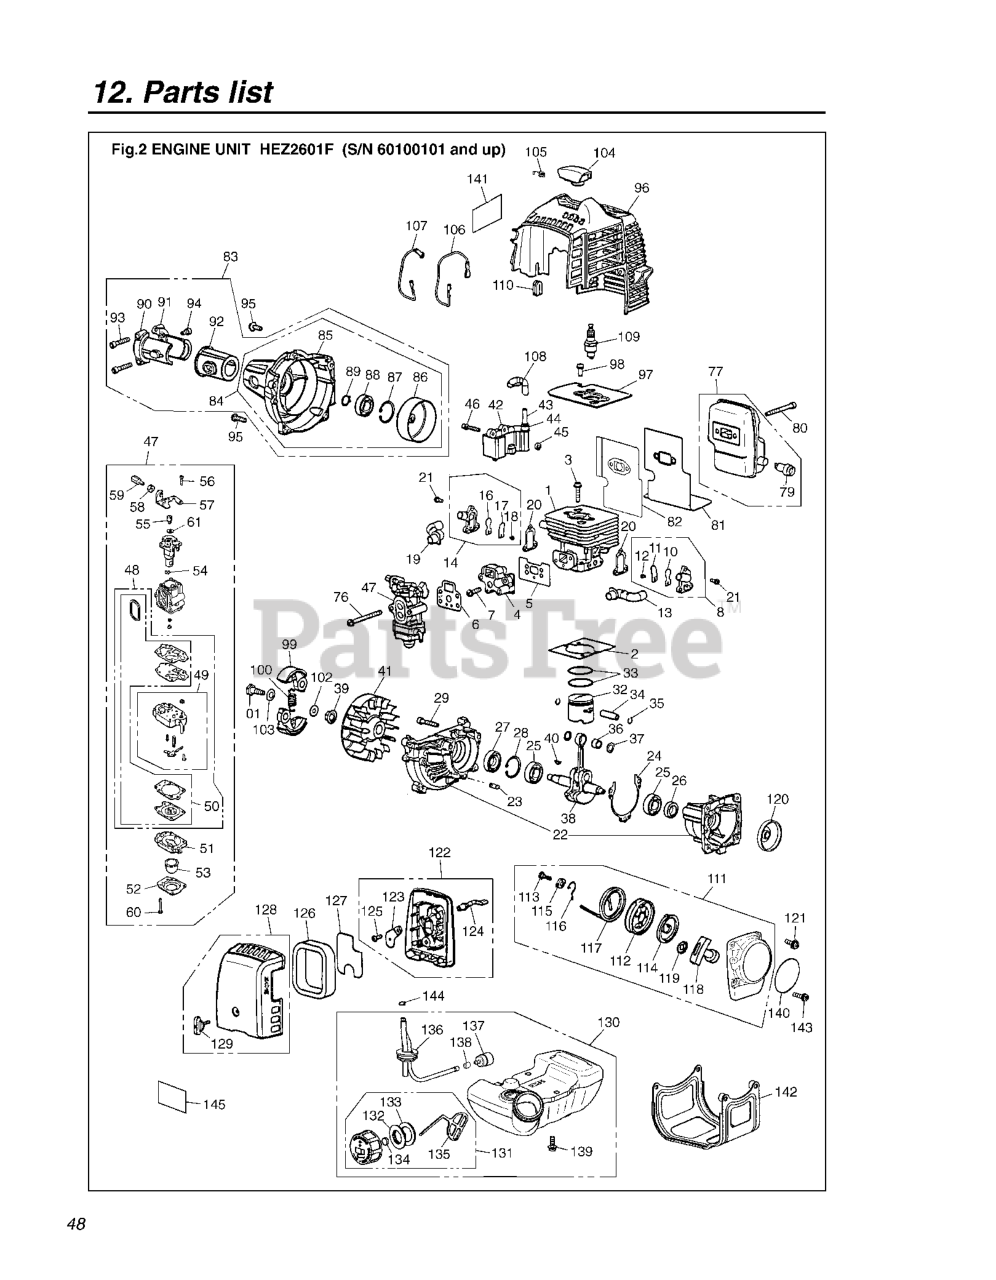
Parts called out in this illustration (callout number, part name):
1	CYLINDER
2	GASKET, BASE
3	BOLT
4	INSULATOR
5	GASKET.INSU
8	REEDVALVE (S) ASSY
10	REEDVALVE
13	PIPE AIR (S)
14	REEDVALVE (F) ASSY
16	REEDVALVE
19	PIPE AIR (F)
20	GASKET, VALVE
21	BOLT
22	CRANKCASE-C
23	PIN
24	GASKET.CASE
27	SEAL
34	PIN***
38	CRANKSHAFT COMP(RPLS481042000)
39	NUT
40	KEY
44	CAP
45	SPACER
47	CARBURETOR
48	REBUILD KIT
49	CARBURETOR BODY
50	GASKET KIT
52	1OVER
54	RING
55	SWIVEL
56	SCREW
57	BRACKET
58	NUT
59	ADJUSTER
61	WASHER
77	MUFFLER-A***
79	ARRESTER
82	PLATE, MUFFLER
83	HOUSING ASSY
84	COVER-C
85	COVER.FAN
88	BEARING
90	BRACKET(A)-24
91	BRACKET(B)-24
94	BOLT M5X14
96	COVER, ENGINE
104	CAP
107	CORD.EARTH
108	TUBE (RPLS 263072210)
109	PLUG CMR7H
111	RECOIL-A
114	SPRING, SPIRAL
115	COLLAR
116	SWING ARM
119	PLATE.STOPPER
121	BOLT M5X14
122	BODY-A
123	PLATE.CHOKE
125	SCREW
128	AIR FILTER COVER
130	TANK ASSY
131	CAP A
132	HOLDER-A
136	PIPE-C
137	FILTER ASSY
138	CLIP
140	RedMax TBD
142	GUARD (RPLS 481031910,11)
143	BOLT
144	CLIP
